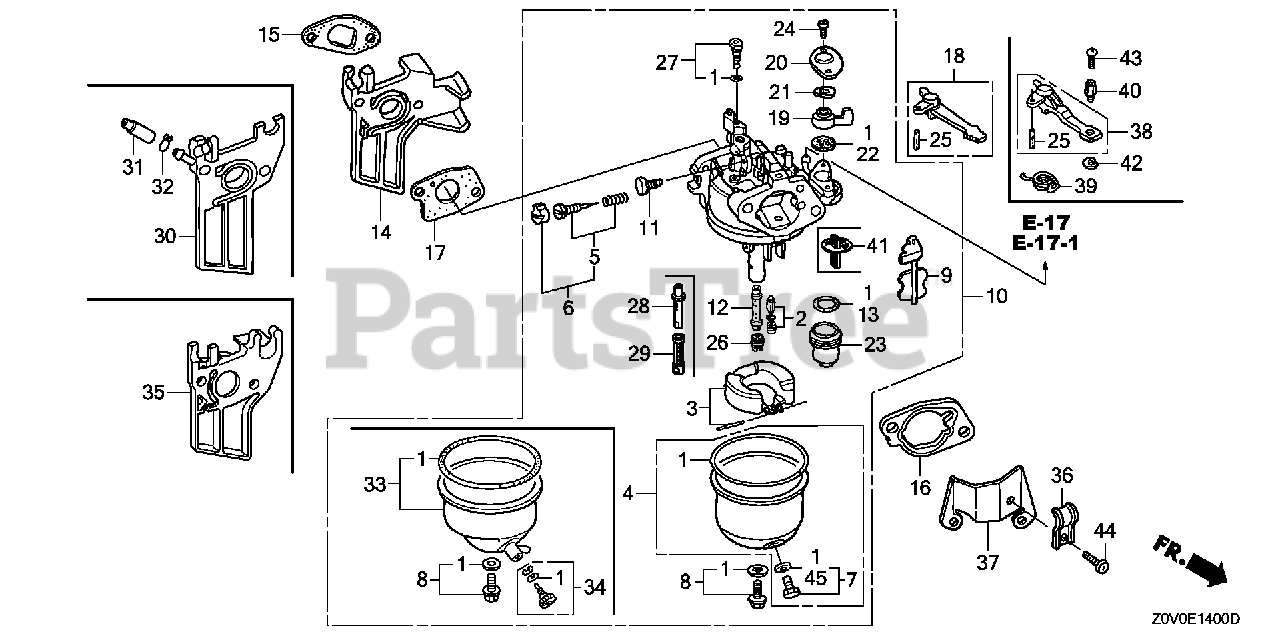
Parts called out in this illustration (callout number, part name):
1	GASKET SET
2	VALVE SET, FLOAT (SEAT NOT INCLUDED)
4	CHAMBER SET, FLOAT
6	SCREW SET, PILOT (CARBURETOR NO.)
7	SCREW SET, DRAIN
8	SCREW SET
10	CARBURETOR ASSY. (BE59J A)
11	SCREW, THROTTLE STOP
12	NOZZLE, MAIN
13	GASKET, FUEL STRAINER CUP
14	INSULATOR, CARBURETOR
15	GASKET, INSULATOR
16	SPACER, CARBURETOR
17	GASKET, CARBURETOR
18	LEVER, CHOKE (STD)
19	LEVER, PETCOCK
20	PLATE, LEVER SETTING
21	SPRING, PETCOCK LEVER
22	GASKET, PETCOCK
23	CUP, FUEL STRAINER
24	SCREW, PAN (3X6)
25	PIN, SPRING (2X12)
26	JET, MAIN (#72)
26	JET, MAIN (#70)
26	JET, MAIN (#75)
27	JET SET, PILOT (#45)
45	WASHER, PLAIN (6.2X10.7 DRAIN)
